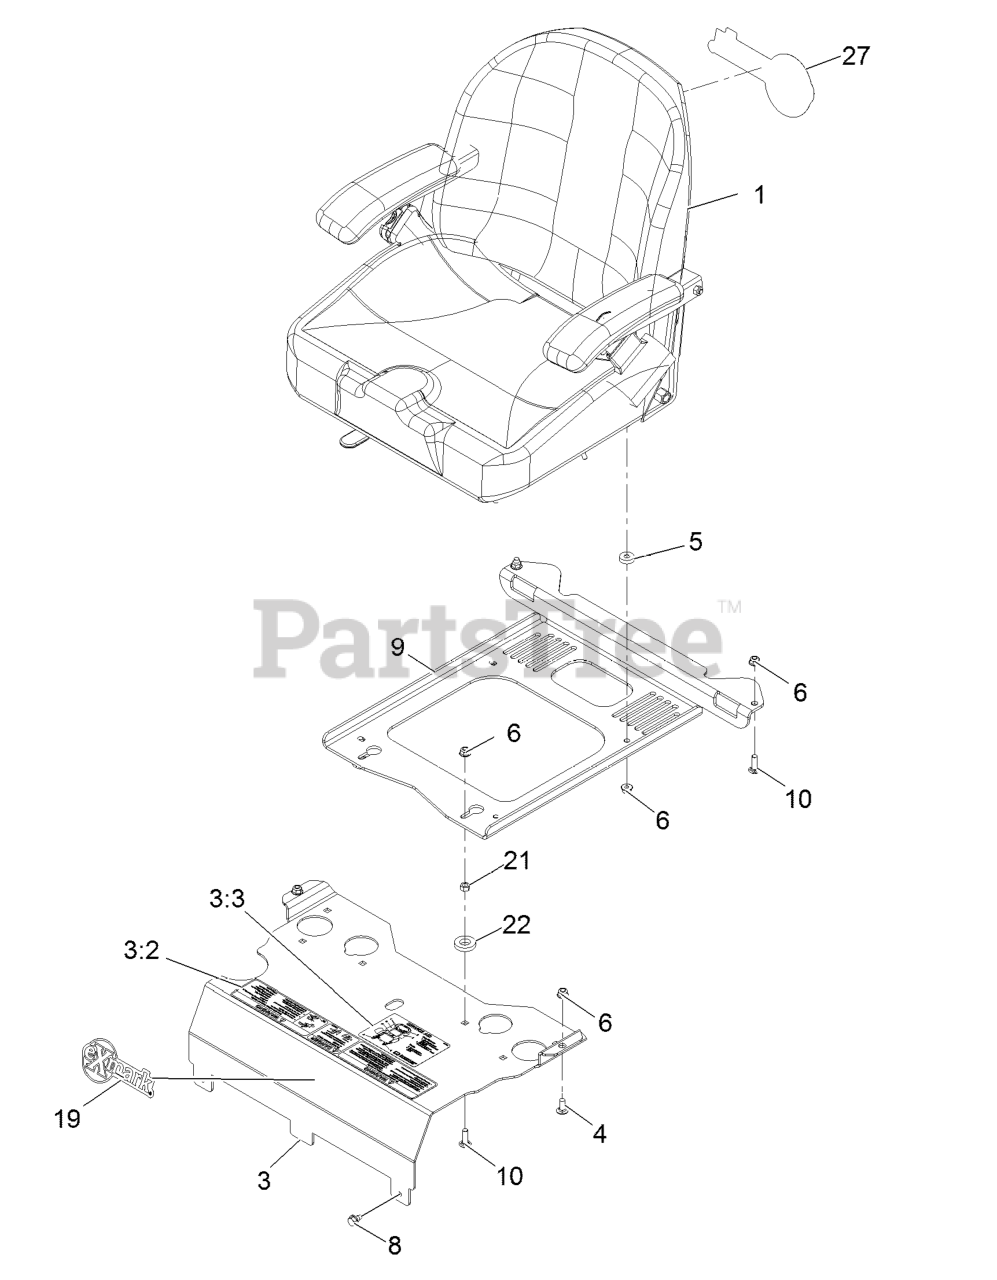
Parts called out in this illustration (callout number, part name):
1	ASM-SEAT, LZE
3	MOUNT-SEAT
3:2	DECAL-CONSOLE
3:3	DECAL-SERVICE AID
4	SCREW-CARR
6	NUT-HF, NI
9	PLATE-SUPPORT, SEAT
10	SCREW-CARR
21	NUT-HEX
27	DECAL,EXMARK LOGO
